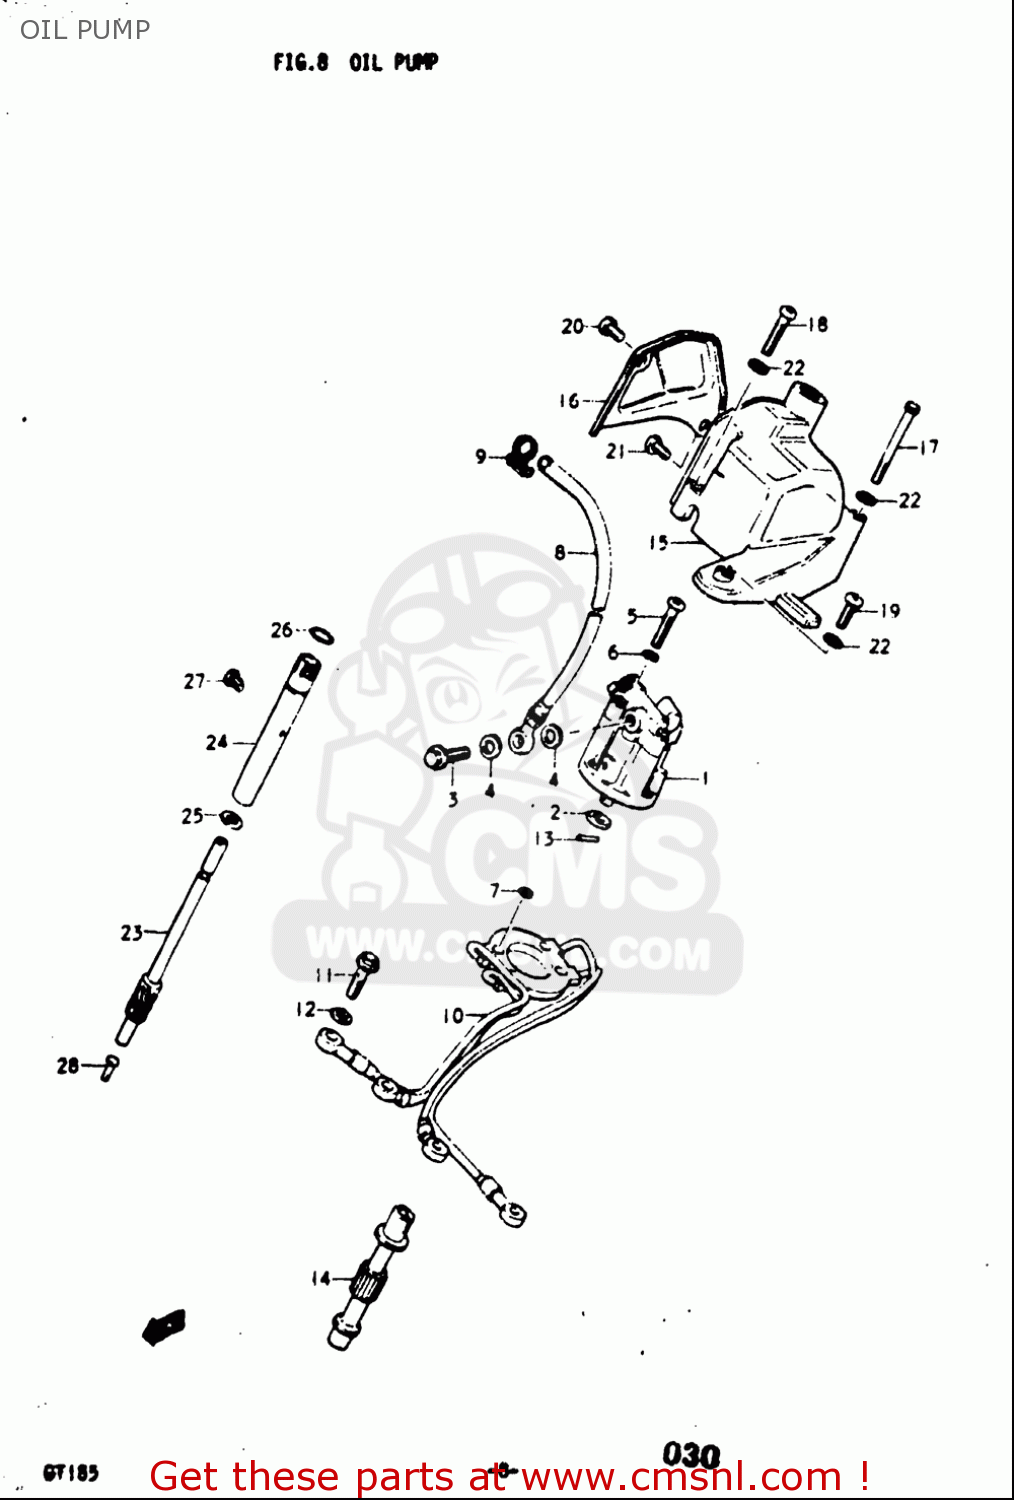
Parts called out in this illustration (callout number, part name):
2	SEAL,OIL(8X16X4)
3	UNION BOLT
4	GASKET(6.2X11X1).2 (NAS)
5	SCREW
6	WASHER,LOCK
7	O RING(D:1.9,ID:3.8)
8	HOSE,INLET
9	CLAMP
11	UNION BOLT
12	GASKET(6.2X11X1).2 (NAS)
13	PIN(3X13.8)
17	BOLT 5X45
18	SCREW
19	SCREW
20	SCREW
21	SCREW
22	WASHER
23	GEAR,TACHOMETER DRIVEN
24	SLEEVE, DRIVEN GEAR
25	WASHER(8X13.7X1)
26	O RING(D:1.3,ID:9.6)
27	BOLT
